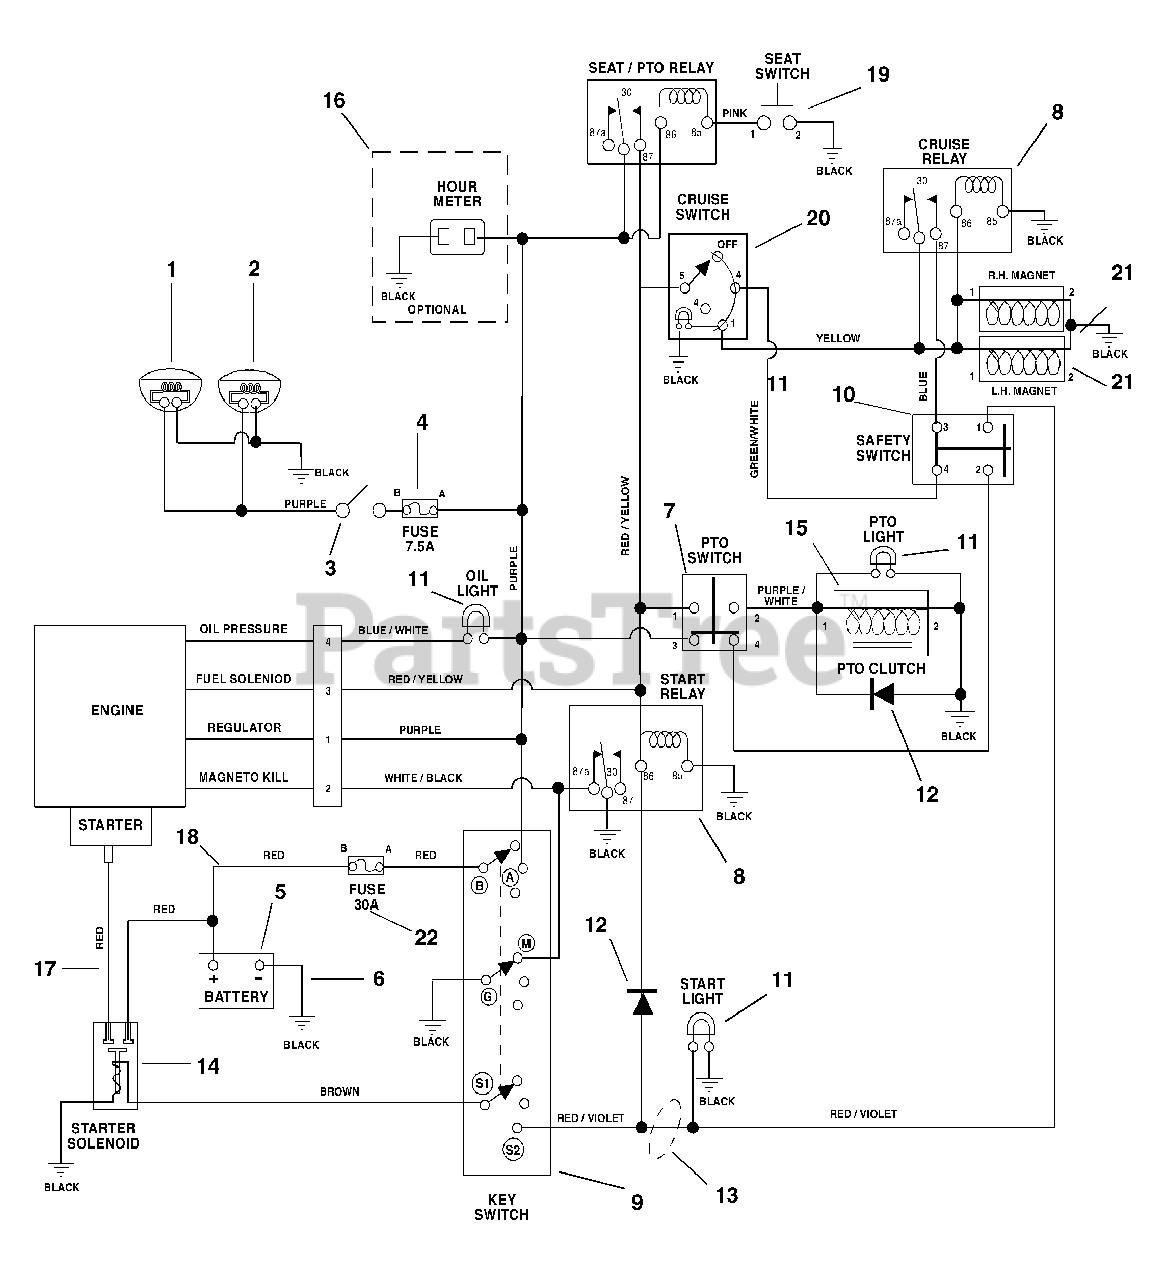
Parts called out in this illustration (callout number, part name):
1	HEADLIGHT- RH
2	HEADLIGHT- LH
3	SWITCH - LIGHT
4	7.5 AMP Fuse
5	BATTERY W/TUBE
6	GROUND CABLE .31X22.00X.31
7	PTO KNOB/ SWITCH ASSY
8	RELAY
9	KEY SWITCH
10	SWITCH,INTERLOCK
11	#194 Bulb
12	MOLDED DIODE PLUG 1 AMP
13	HARNESS-WIRING,HIGH SIERRA
14	SOLENOID
15	CLUTCH, ELECTRIC - WARNER
16	HOUR METER
17	START CABLE 22"
18	STARTER CABLE 6.75"
19	SWITCH- SEAT
20	SWITCH - CRUISE
22	30 AMP Fuse
